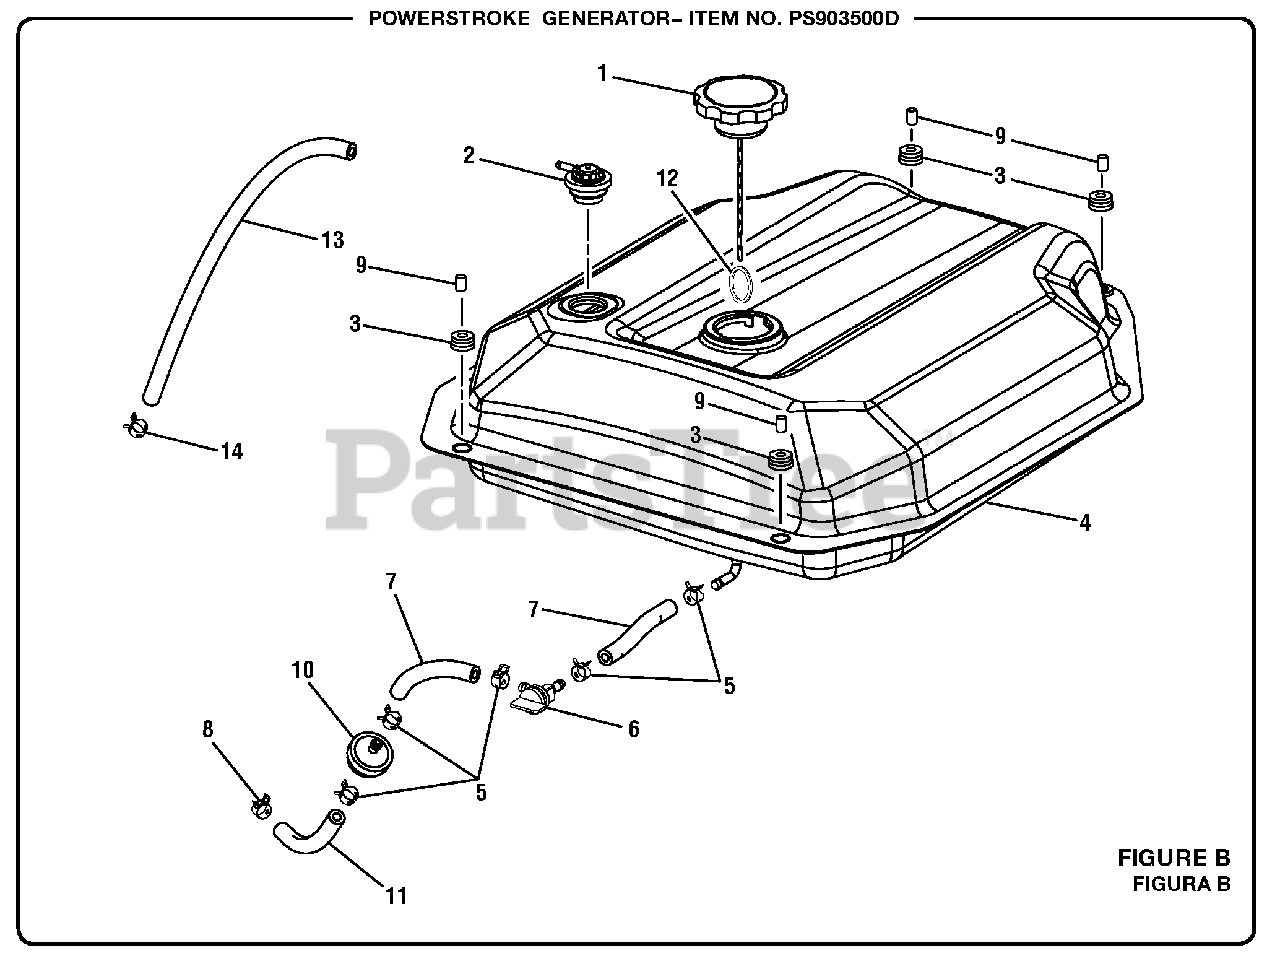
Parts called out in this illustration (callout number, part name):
1	Fuel Tank Cap
2	Fuel Tank Vapor Vent
4	Fuel Tank
5	Fuel Line Clamp
6	Fuel Shut Off Valve
7	Fuel Line (90 mm)
8	Fuel Clamp (5/16 in.)
10	Fuel Line Filter
11	Fuel Hose (150 mm)
12	Ring Clip
13	Vent Hose
14	Fuel Line Clamp (7/16 in.)
